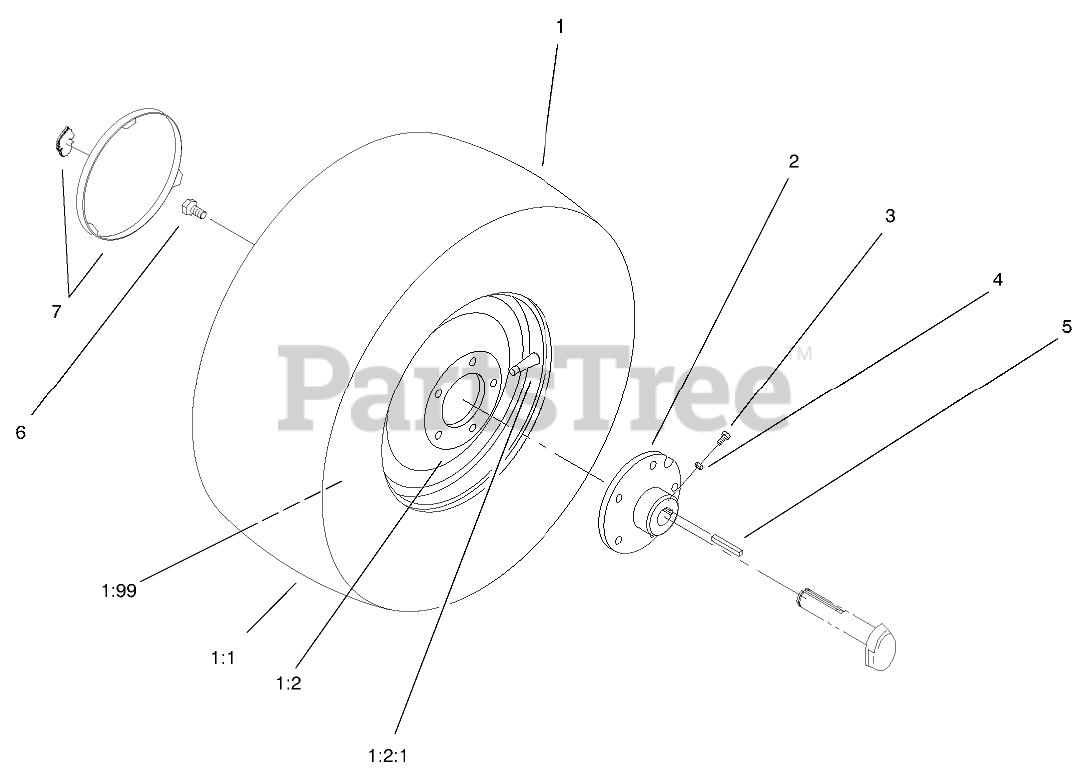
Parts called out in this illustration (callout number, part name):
1	Wheel&tire ASM,Rear
1:2	WHEEL
1:2:1	VALVE
1:99	TUBE-INNER
2	HUB-WHEEL
3	SCREW-SET, SQH
4	NUT-JAM
5	KEY-SQUARE
6	BOLT-LUG
7	Hubcap ASM-12", Ygt (Horsehead Logo)(Only On: 72106)
